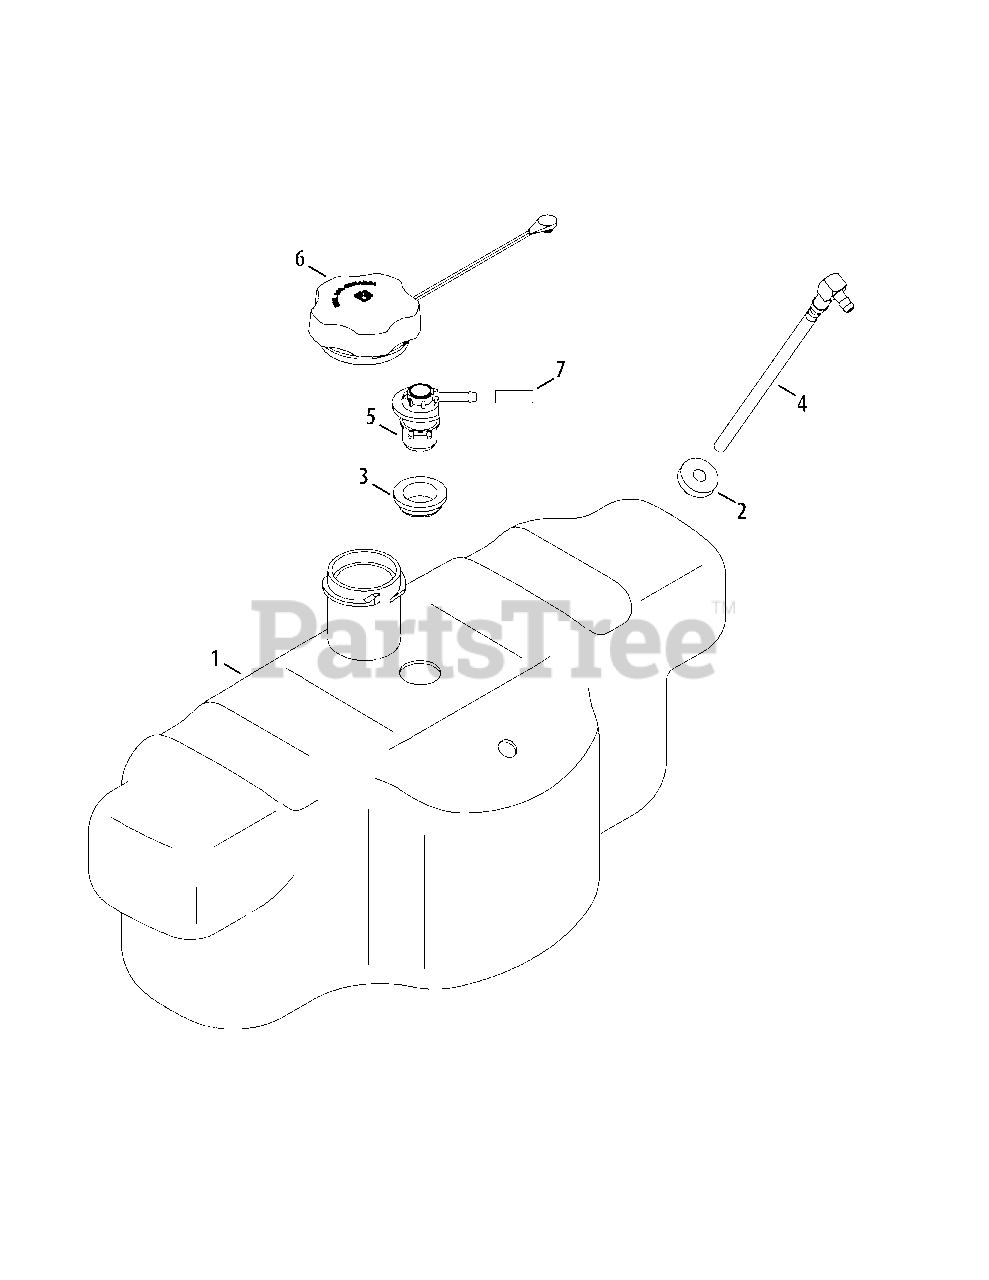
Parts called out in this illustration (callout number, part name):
1	Fuel Tank
2	Fuel Tank Bushing
3	Rubber Grommet
4	Fuel Pickup Fitting
5	Rollover Valve
6	Fuel Cap
7	Vent Hose
